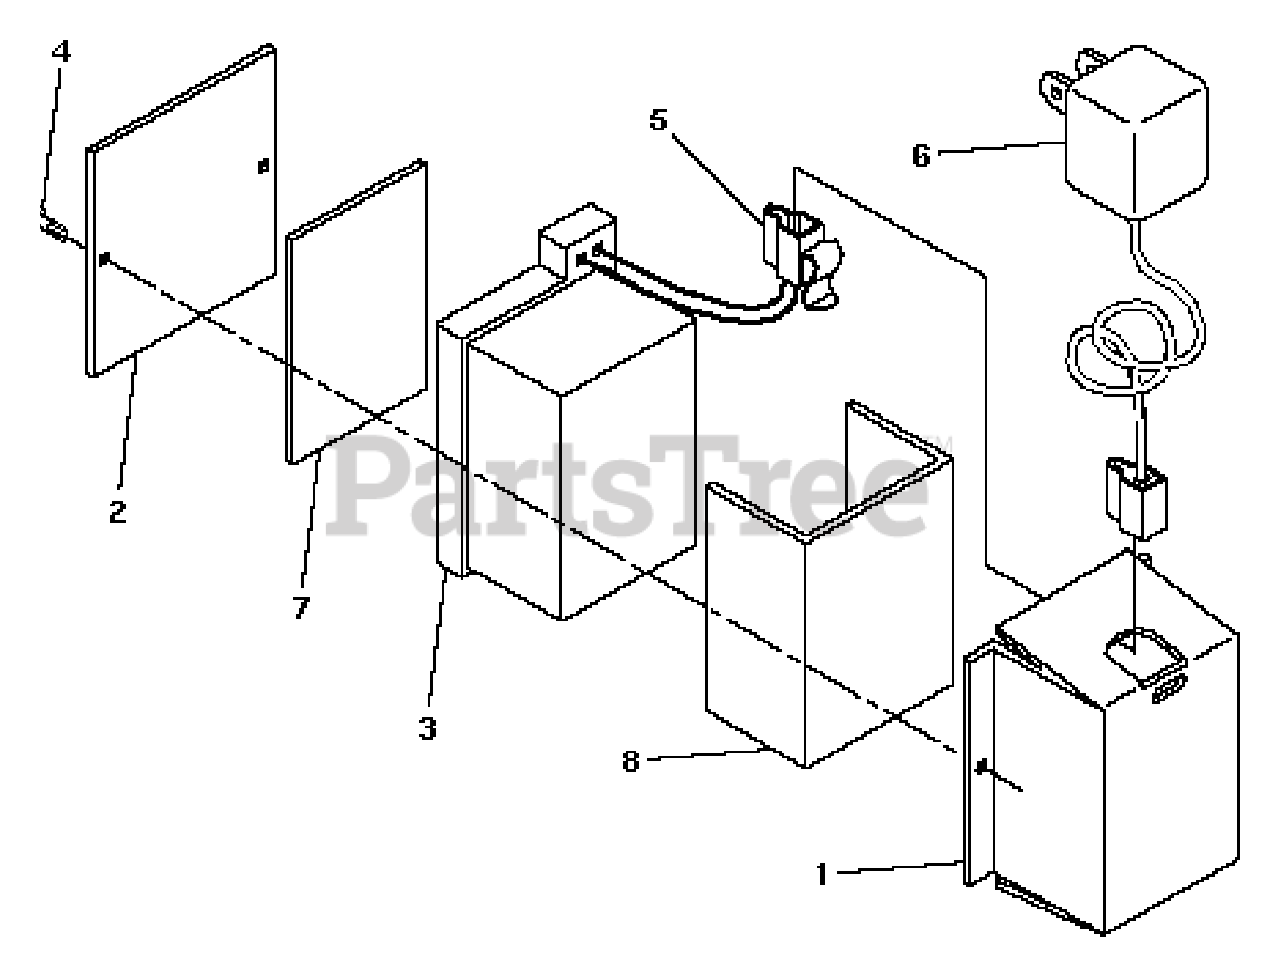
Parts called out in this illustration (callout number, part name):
1	Battery Bracket
2	Battery Cover
3	Battery Kit
4	Hex Washer Head Screw #10-24 x 1/2
5	Connector Mounting Clip
6	Battery Charger
7	Battery Pad
8	Battery Wrap
